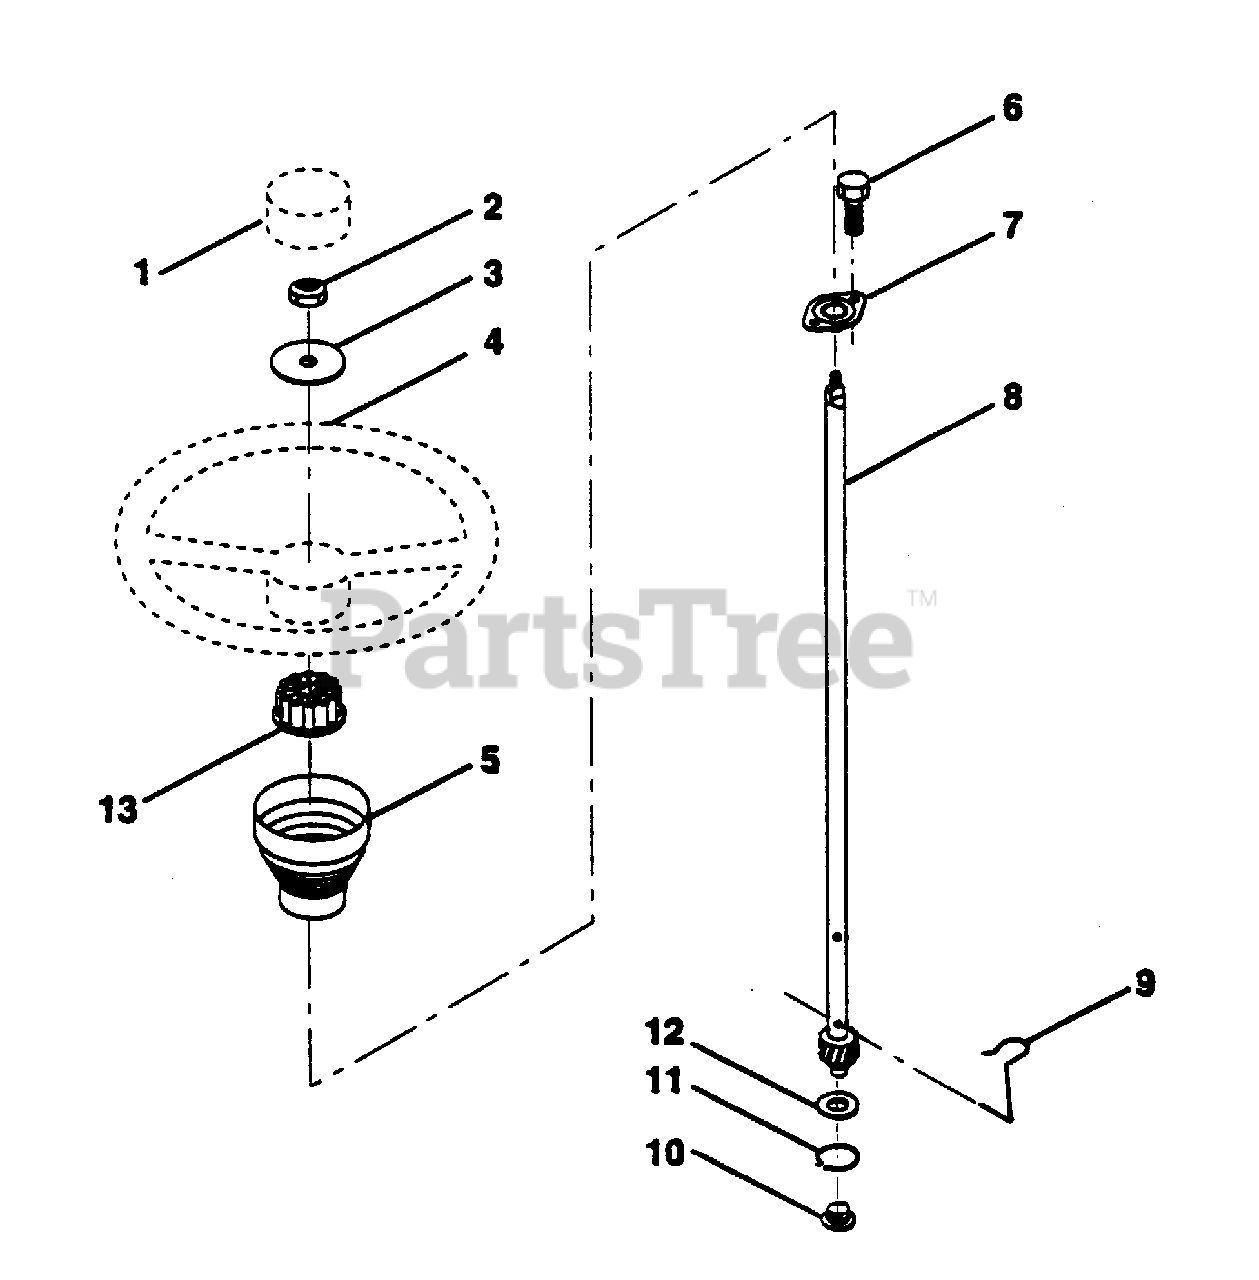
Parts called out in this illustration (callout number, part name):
1	Insert, Wheel, Steering
2	Nut, Lock 3/8-24 UNF
3	Washer 12/32 x 2-3/8 x 8 Ga.
4	Wheel, Steering
5	Sleeve, Steering
6	Screw, Hex #10-16 x 1/2 TY-B
7	Bushing, Steering
8	Shaft, Steering
9	Clip, Steering
10	Bushing, Lower, Steering
11	Ring, Retaining
12	Washer 21/32 x 1 x 16 Ga.
13	Adaptor, Wheel, Steering
